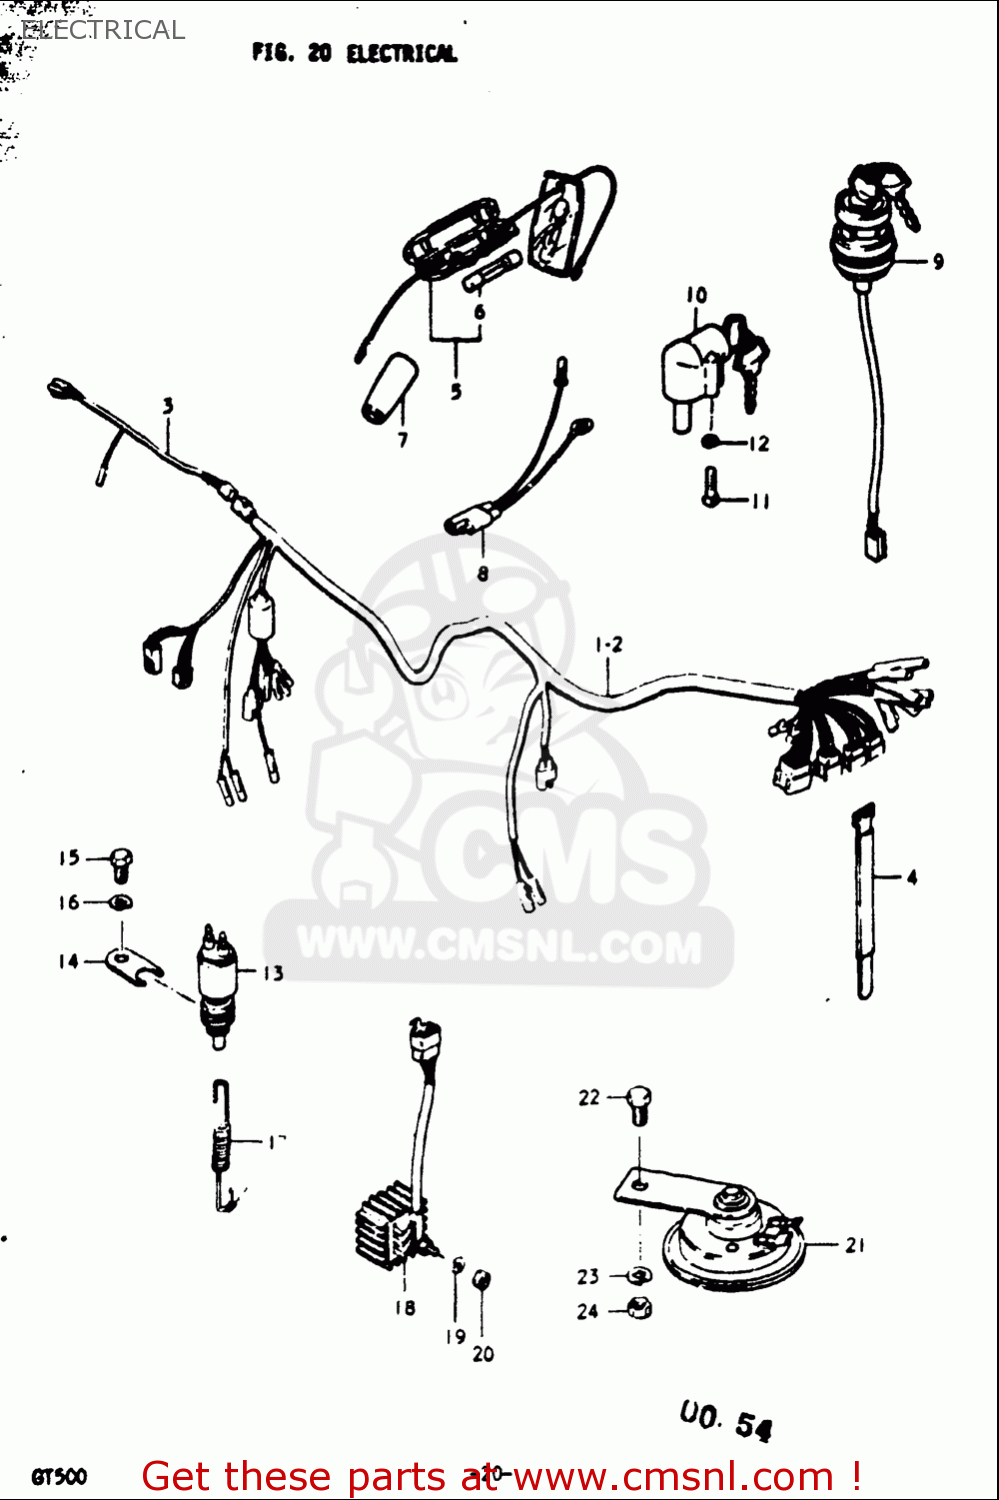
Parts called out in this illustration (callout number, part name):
4	CLAMP
5	CASE ASSY,FUSE
6	FUSE(15A)
8	WIRE,BATTERY LEAD
9	SWITCH ASSY,IGNITION
10	LOCK ASSY,STEERING
11	SCREW
12	WASHER,LOCK
13	SWITCH ASSY,BRAKE LAMP
15	BOLT
16	WASHER,LOCK
17	SPRING
18	RECTIFIER ASSY
19	WASHER,LOCK
20	NUT
22	BOLT
23	WASHER,LOCK
24	NUT
